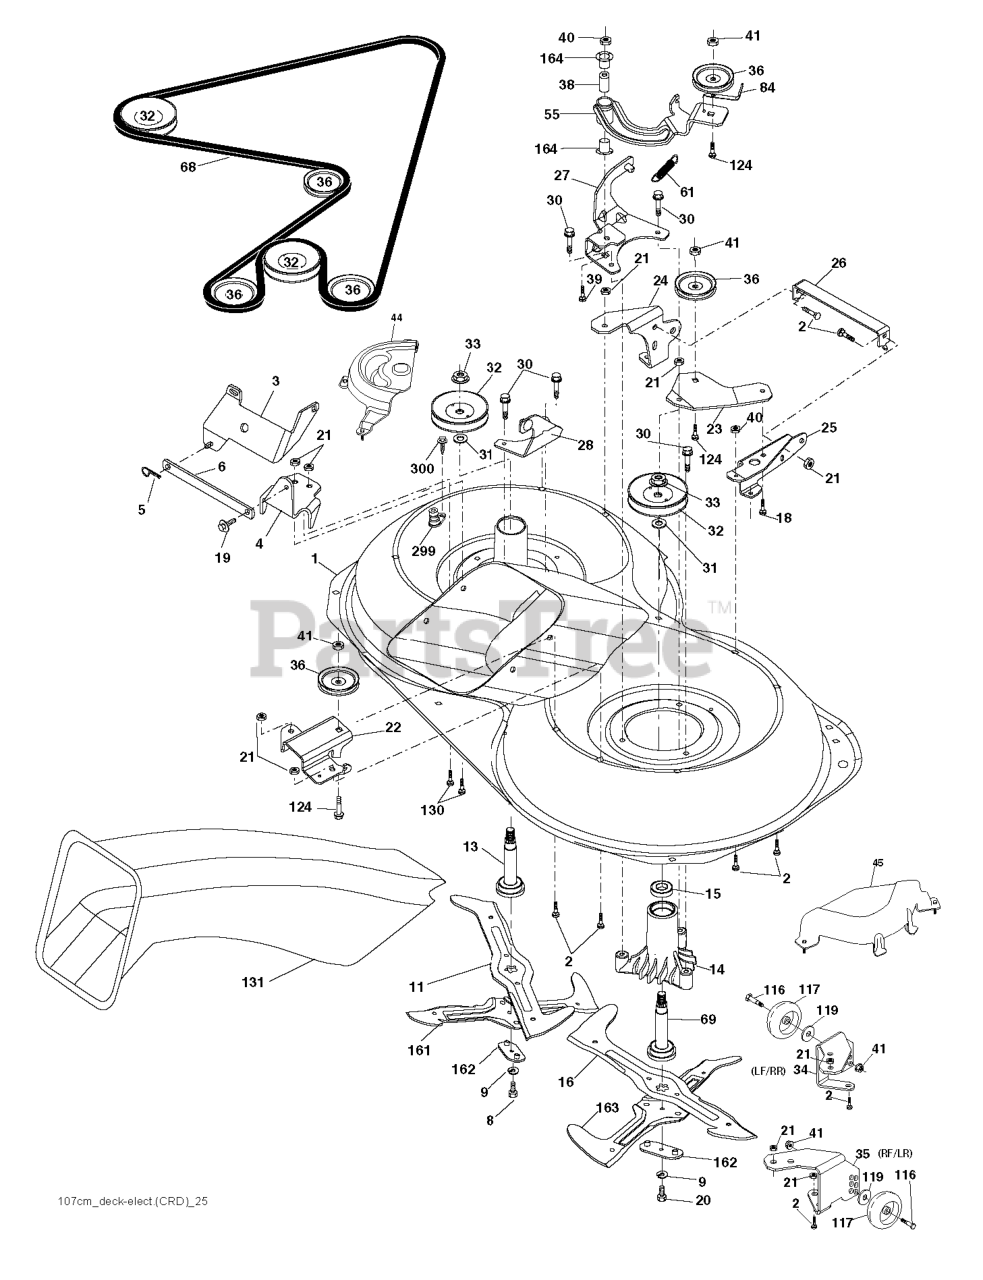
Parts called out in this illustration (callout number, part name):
1	Housing Asm. Mower 107 CRD
2	RP BOLT 5/16-18 X3/4 ZN/YEL GR
3	BRACKET.ASM.BAR.SWAY.CHASS
5	RETAINER-SPRNG RB
6	BAR.SWAY.92.CRD
8	BOLT.3/8-24X1.25 GR8
9	LOCKWASHER
11	BLADE.3N1.LH.CRD
13	SHAFT ASM VENT
14	HOUSING.MANDREL.VENTED (MACHD)
16	BLADE.3N1.RH.CRD
19	BOLT SHD 5/16-18
20	BOLT.3/8-24X1.25GR8. LHTHRD
21	LOCKNUT
22	BRACKET.IDLER.RR.107.CRD
24	BRACKET
25	BRACKET RF
26	SUPPORT
28	BRACKET
30	SCREW, WASHER HEAD
31	WASHER.SPACER.MANDREL
32	PULLEY.MANDREL.4.80 PD.2006
33	NUT.FLANGE.LOCK.TOP
34	BRACKET
35	BRACKET
36	PULLEY.IDLER.4.25
41	NUT LOCK FLG 3/8-16 UNC
55	ARM.IDLER.107.CRD
61	SPRING
68	HEX-BELT 107 MOWER
69	SHAFT.ASM.W/LWR.BRG.RH.THREAD
84	KEEPER, BELT IDLER
116	BOLT.SHOULDER.3/8-16X3-5/8.
117	RP WHEEL. GUAGE RALLY
119	WASHER
124	BOLT.3/8-16X1.50
130	BOLT.CARR.SQNK.5/16-18UNC.X3/4
131	CHUTE BAGGER
163	BLADE.CROSS.RH.CRD.107
164	BRNG T
299	PORT.WASHOUT
300	SCREW.TT.#10-32X.5.3/8.FLANGE
